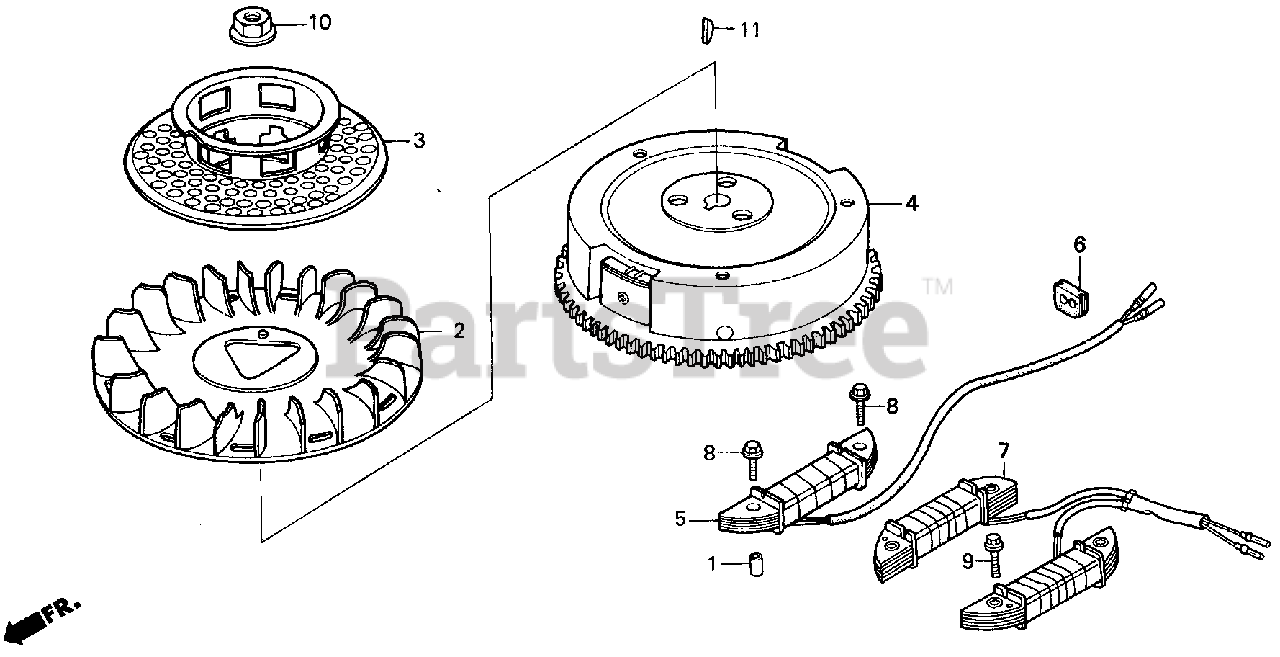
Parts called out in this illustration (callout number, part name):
2	FAN, COOLING
3	PULLEY, STARTER
4	FLYWHEEL
10	NUT, SPECIAL (16MM)
11	KEY, SPECIAL WOODRUFF (25X18)
